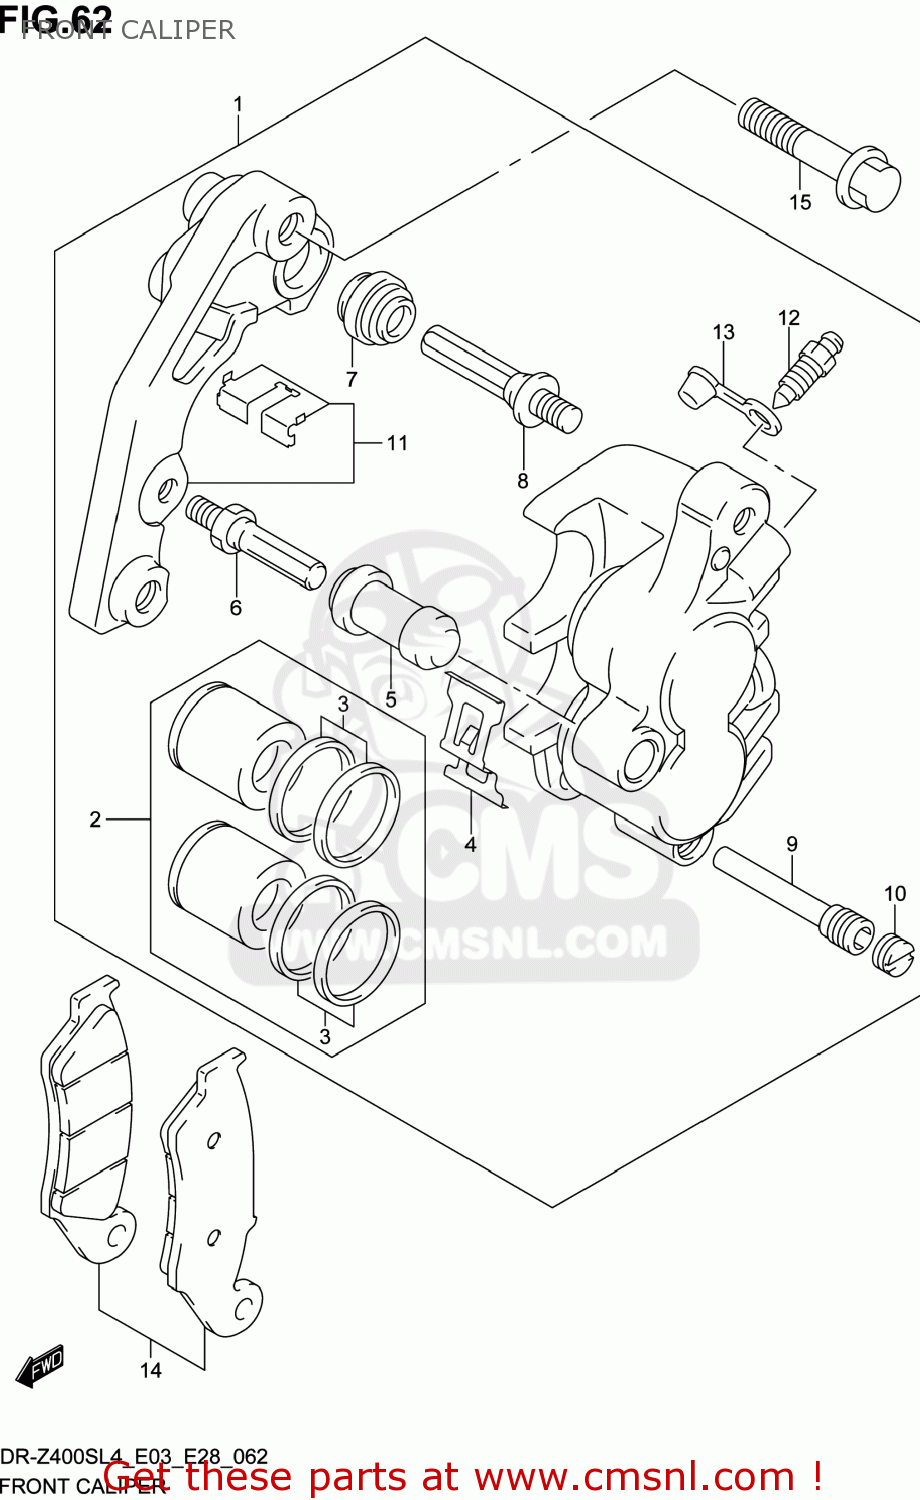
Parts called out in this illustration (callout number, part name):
1	CALIPER ASSY,FR,L
2	PISTON SET
3	SEAL SET,PISTON
4	SPRING,PAD
5	BOOT
6	PIN,BOLT
7	BOOT
8	PIN
9	PIN,HANGER
10	PLUG,PIN
11	BRACKET
12	BLEEDER
13	CAP,BLEEDER
14	PAD SET (NAS)
15	BOLT(8X40)
